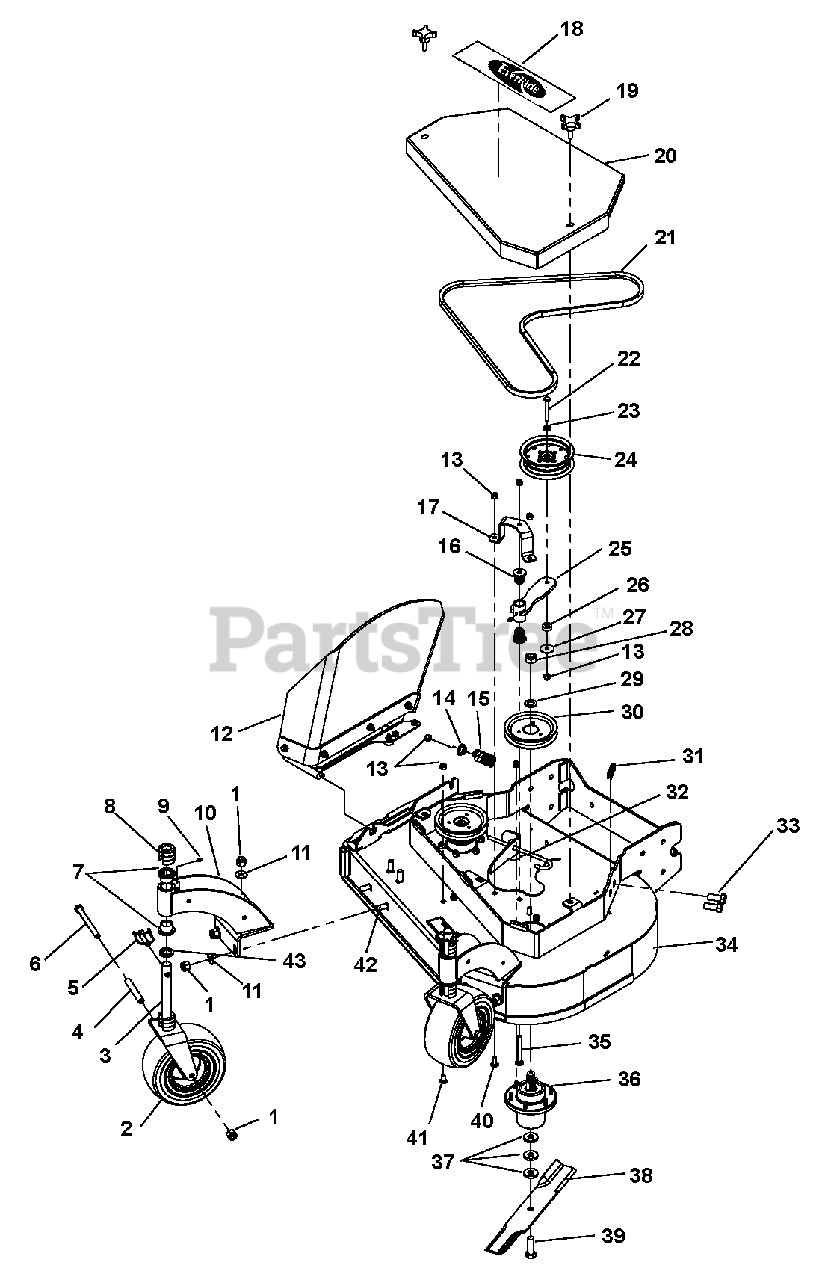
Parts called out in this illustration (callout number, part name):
1	Locknut, .50-13 Nyloc
2	Assy, Wheel & Tire - 9 x 3.5
3	Weldment, Caster Yoke
4	Tube, Caster Axle
5	Pin, LNC .438 x 2.00
6	Bolt, 50-13 x 5.50 Hex Grade 5
7	Bearing, Flange 1.00 x 1.25 x 1.00
8	C-Spacer, 1.00 x 1.77 x .500
9	Fitting, .25-28 Straight Grease Zerk
10	Weldment, Strut Front
11	Washer, .438 Reg Flat
12	Assembly, Discharge Shield
13	Locknut, .375-16 Nyloc
14	Keeper, Spring
15	Spring,1.22 x .162 x 2.50
16	Bearing, Flange M10 x M25 x M27 Fluted
17	Brace, Tensioner Arm
18	Decal, 9" EverRide Logo Small
19	Knob, .375 x 1.25 - 4 Prong
20	Weldment, Belt Shield 36 FXWLK
21	Belt, HB 77.5 Elbow AMD OHR
22	Bolt, .38-16 x 2.75 Hex Grade 5
23	Washer, .406 x .813 x .065 Flat
24	Pulley, Flat 5.0 x .38 w/ Bearing
25	Weldment, Idler 36 FXWLK
26	Bushing, .380 x 1.00 x .410
27	Washer, .375 x 1.50 x .063 Flat
28	Locknut, .75-16 Crown
29	Washer, .75 x 1.3125 x .113
30	Pulley, Spline Spindle Offset
31	Trim, 2" Trim-Lok Edge
32	J-Bolt, .375-16 x 7.88
33	Bolt, .625-11 x 1.50 Hex Grade 8
34	Assembly, Deck 36" Wasp w/Decal
35	Bolt, .375-16 x 3.50 Grade 5
36	Assembly, Spindle Housing
37	Washer, Blade
38	Blade, 18"
39	Bolt, .625-11 x 2.00 Hex Grade 8
40	Bolt, .375-16 x 1.00 Grade 5
41	Bolt, .38-16 x .75 Round Head Square Neck Grade 5
42	Bolt, .50-13 x 1.50 Round Head Square Neck Grade 5
43	Bushing, 1.03 x 1.50 x .179 Y
